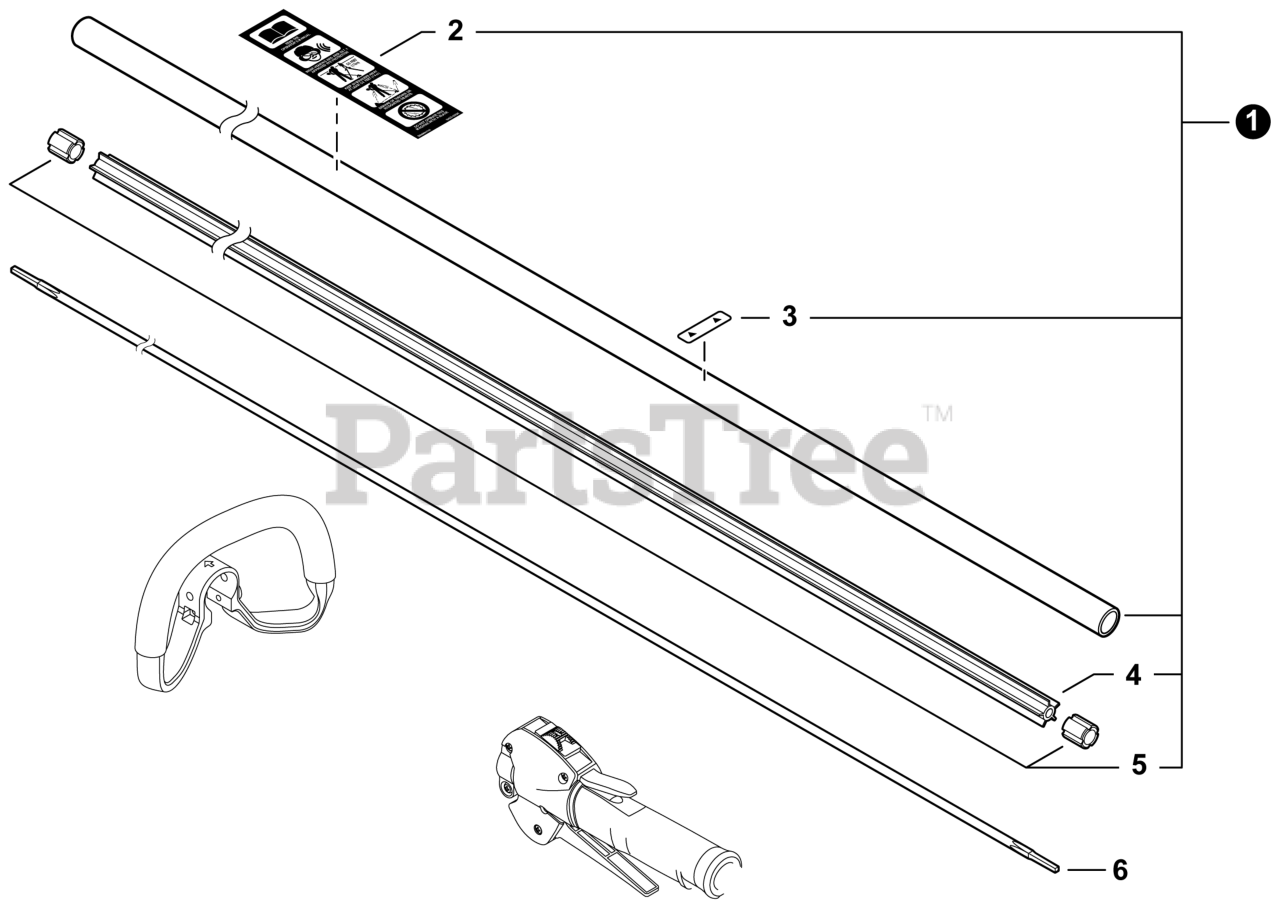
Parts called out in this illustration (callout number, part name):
1	MAIN PIPE ASSY
2	LABEL - CAUTION
3	LABEL - ALIGNMENT
4	LINER, FLEXIBLE 21.6×1420
6	DRIVESHAFT - FLEXIBLE
